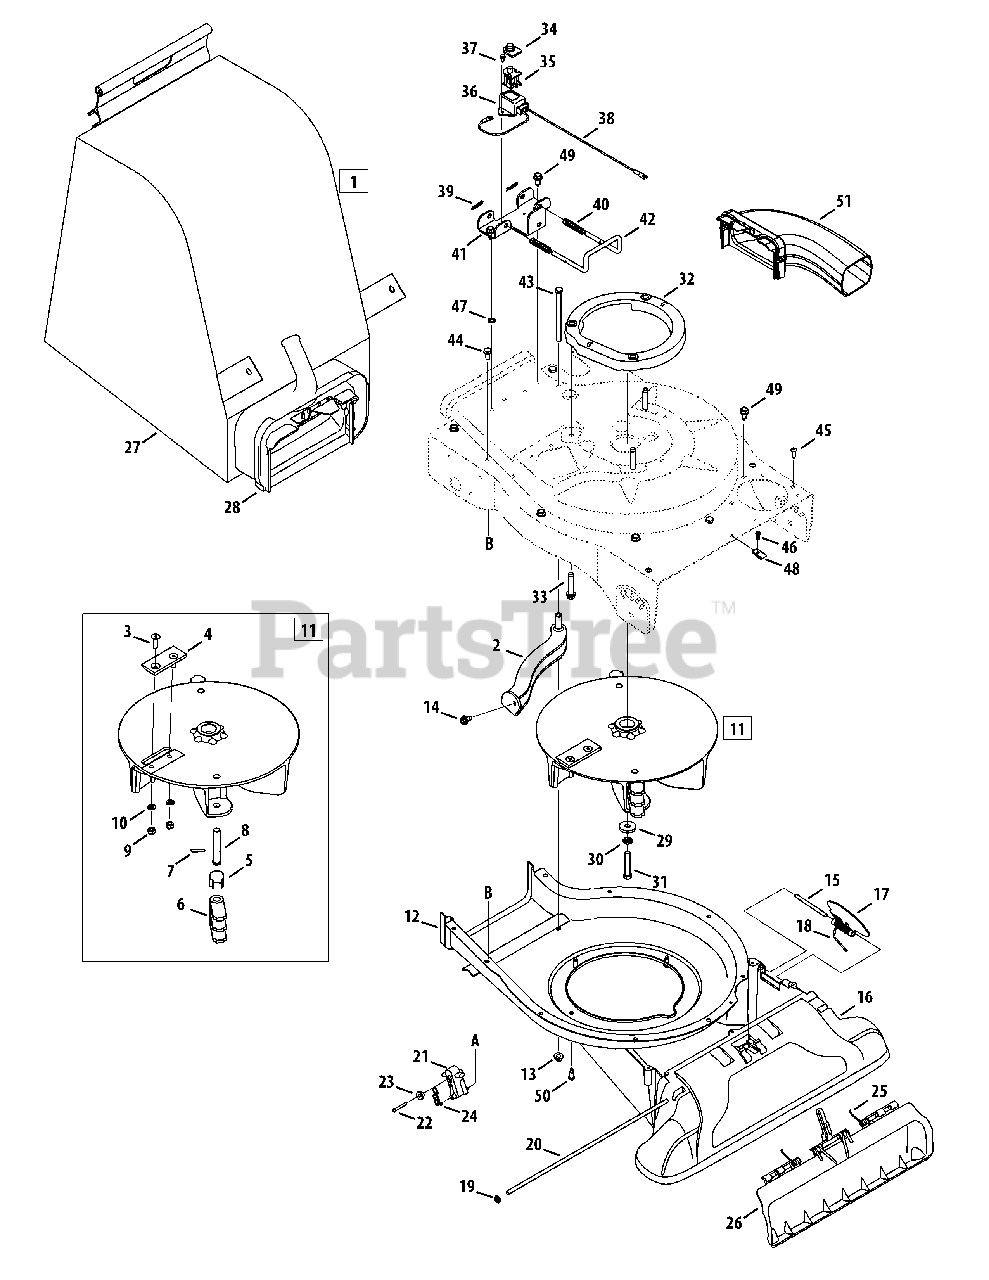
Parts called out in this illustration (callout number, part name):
1	Bag Assembly
2	Screen Assembly
3	Hex Screw 5/16-24 x 1.0
4	Chipper Blade
5	Pin Clip
6	Flail
7	Spiral Pin
8	Clevis Pin
9	Lock Nut, 5/16-24
10	Lock Washer, 5/16
11	Impeller Assembly
12	Lower Flail Housing
13	Flange Lock Nut 5/16-18
14	Screw, 5/16-18 x.500
15	Hinge Pin
16	Nozzle
17	Base Adapter Door
18	Torsion Spring
19	Cap Speed Nut 1/4
20	Pivot Rod
21	Nozzle Door Lever
22	Hex Screw, #8-18 x 1.25
23	Shoulder Spacer
24	Extension Spring
25	Nozzle Door Torsion Spring
26	Nozzle Door
27	Bag
28	Chute Assembly
29	Flat Washer.375 ID x 1.25 OD
30	Lock Washer 3/8
31	Hex Cap Screw, 3/8-24 x 2.75
32	Engine Spacer Assembly
33	Screw, 3/8-16 x 1.875
34	Switch Cover
35	Safety Switch
36	Safety Switch Cover
37	Hex Washer Screw #10-16 x.50
38	Wire Harness
39	Cotter Pin
40	Compression Spring
41	Mounting Bracket
42	Lock Rod
43	Hex Cap Screw 5/16-18 x 4.5
44	Hex Cap Screw 5/16-18 x.625
45	Screw, #12-16 x.750
46	Screw #10 - 16 x.500
47	External L-Washer 5/16
48	Speed Nut
49	Hex Index Screw, 5/16-12 x.750
50	Shoulder Screw, #12-24 x .30 x .46
51	Blower Chute
